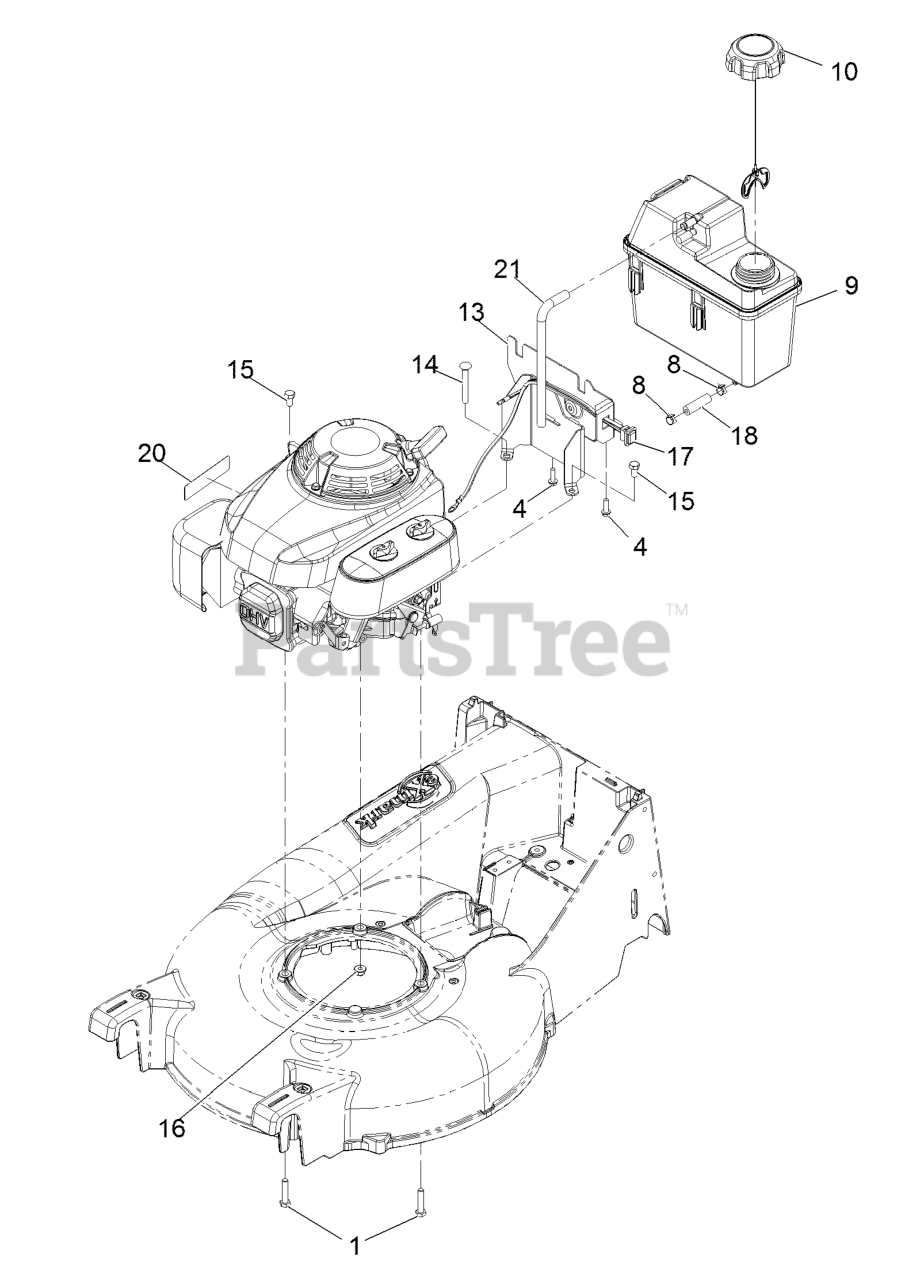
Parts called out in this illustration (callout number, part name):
1	SCREW-HH
4	SCREW-HWH
8	CLAMP-HOSE
9	TANK-FUEL
13	BRACKET ASM
14	SCREW-CARR
15	SCREW-HH
16	NUT-HF, NI
17	HARNESS,RUN/STOP
18	HOSE-FUEL
20	DECAL-ARRESTER, SPARK
21	HOSE-VENT, CANISTER
